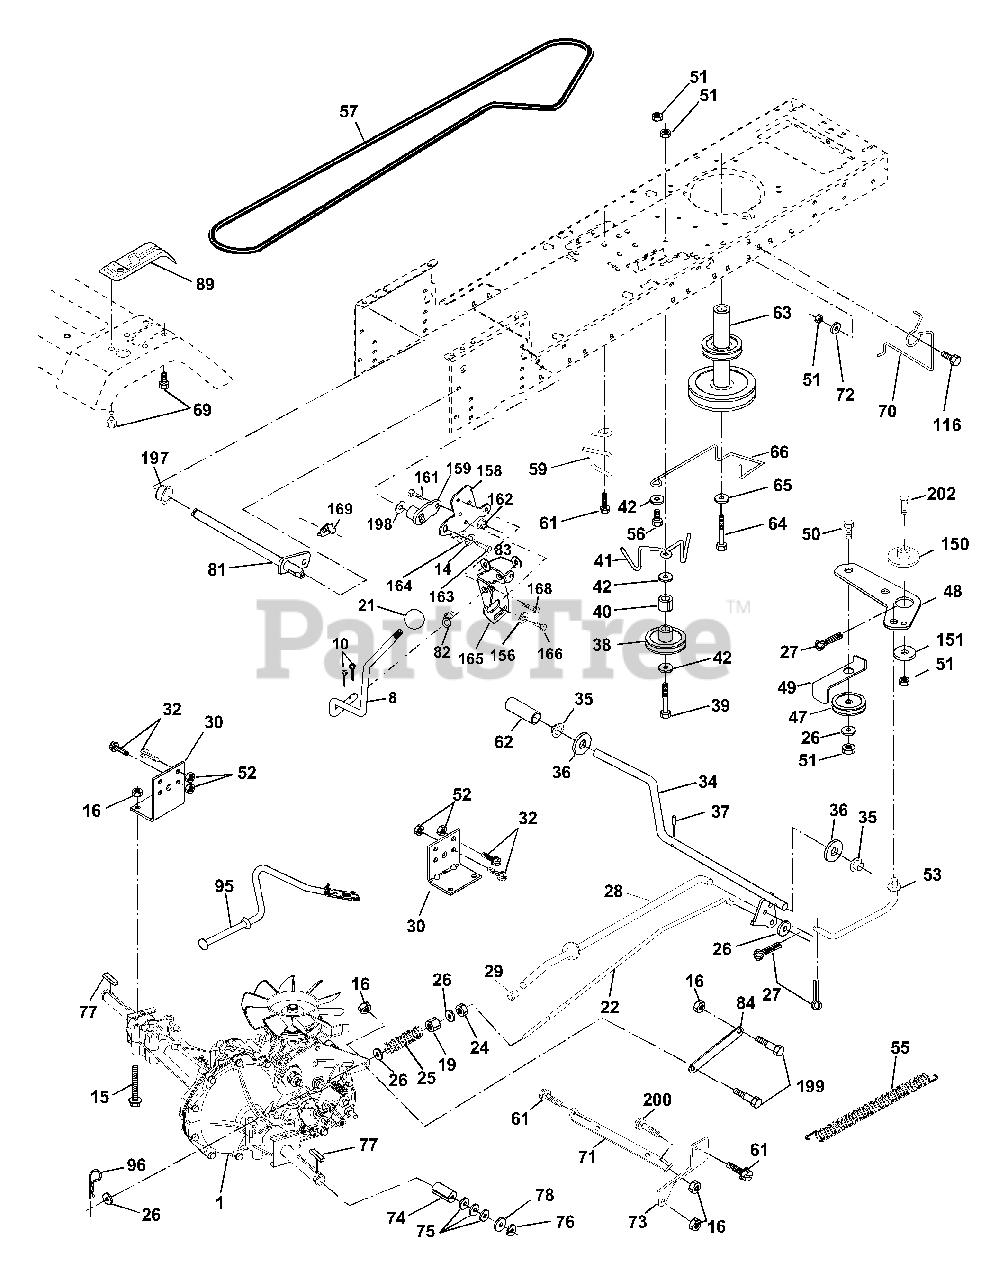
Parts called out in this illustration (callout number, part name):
8	Rod Shift Hydro LT
10	Pin Cotter 1/8 x 1 CAD
14	Washer Lock Hvy Helical
15	Bolt, Hex FLGHD 5/16-18 Gr. 5
16	Nut Lock Hex W/Ins 5/16-18 Unc P
18	Bolt Fin Hex 3/8-16 Unc x 1 Gr. 5
19	Nut Lock Hex W/Wsh 3/8-16 Unc
21	Knob, Round 1/2-13
22	Rod, Brake Hydro
24	Nut
25	Spring, Brake Rod
26	Washer
27	Pin Cotter 1/8 x 3/4 CAD.
28	Rod, Parking Brake
29	Cap, Parking Brake
30	Bracket, Transaxle
32	Bolt Hex Hd 5/16-18 Unc x 3/4
34	Shaft, Foot Pedal
35	Bearing, Nylon
36	Washer
37	Pin, Roll
38	Pulley, Idler, Flat
39	Bolt
40	Spacer, Split
41	Keeper, Belt Idler
42	Washer 13/32 x 13/16 x 12 Gauge
47	Pulley, Idler, V-Groove
48	Bellcrank Clutch Grnd Drv STL
49	Retainer, Belt
50	Bolt
51	Nut Crownlock 3/8-16 UNC
52	Nut Crownlock 5/16-18 UNC
53	Link, Clutch
55	Spring, Return, Clutch
56	Bolt Fin Hex 3/8-16 UNC x 1-1/4
57	V-Belt, Ground Drive
59	Keeper, Center Span
61	Screw 3/8-16 x 3/4
62	Cover, Pedal
63	Pulley, Engine
64	Bolt, Hex
65	Washer
66	Keeper Belt Engine
69	Screw
70	Guide Belt
71	Strap Torque Lh Hydro
72	Washer 13/32 x 1-1/4 x 12 Gauge
73	Strap Torque Rh Hydro
74	Spacer, Axle
75	Washer 25/32 x 1-1/4 x 16 Gauge
76	E-Ring
77	Key, Square
78	Washer 25/32 x 1-5/8 x 16 Gauge
81	Shaft Asm. Cross Hydro
82	Spring Torsion T/A
83	Washer 17/32 x 3/4 x 16 Ga.
84	Link Transaxle
89	Console, Hydro
95	Control Asm Bypass Hydro
96	Retainer Spring 1" Zinc/Cad
116	Bolt Rdhd Sq Neck 3/8-16 x 1.25
150	Bushing Bellcrank Grd Drive
151	Washer 13/32 x 2 x 10 Ga.
156	Washer Srrted 5/16 ID x 1.125
158	Bracket Shift Mount
159	Hub Tapered Flange Shift Lt
161	Bolt Rdhd Sqnk 1/4-20 x 3/4 Gr 5
162	Nut Crownlock 1/4-20 Unc
163	Bolt Hex Fin 1/4-20 Unc x 1 Gr 5
164	Washer 5/8 x .281 x 10 Ga
165	Bracket Pivot Lever
166	Screw 5/16-18 x 5/8
168	Bolt Shoulder 5/16-18 x .561
169	Plate Fastening Lt
197	Nyliner Snap-In 5/8" ID
198	Washer Nyl 7/8 ID x .105"
199	Bolt Shoulder 5/16-18 UNC
200	Bolt Rdhd Sqnk 5/16-18 UNC x 1
202	Bolt Carr. Sh 3/8-16 x 1-1/2 Gr. 5
